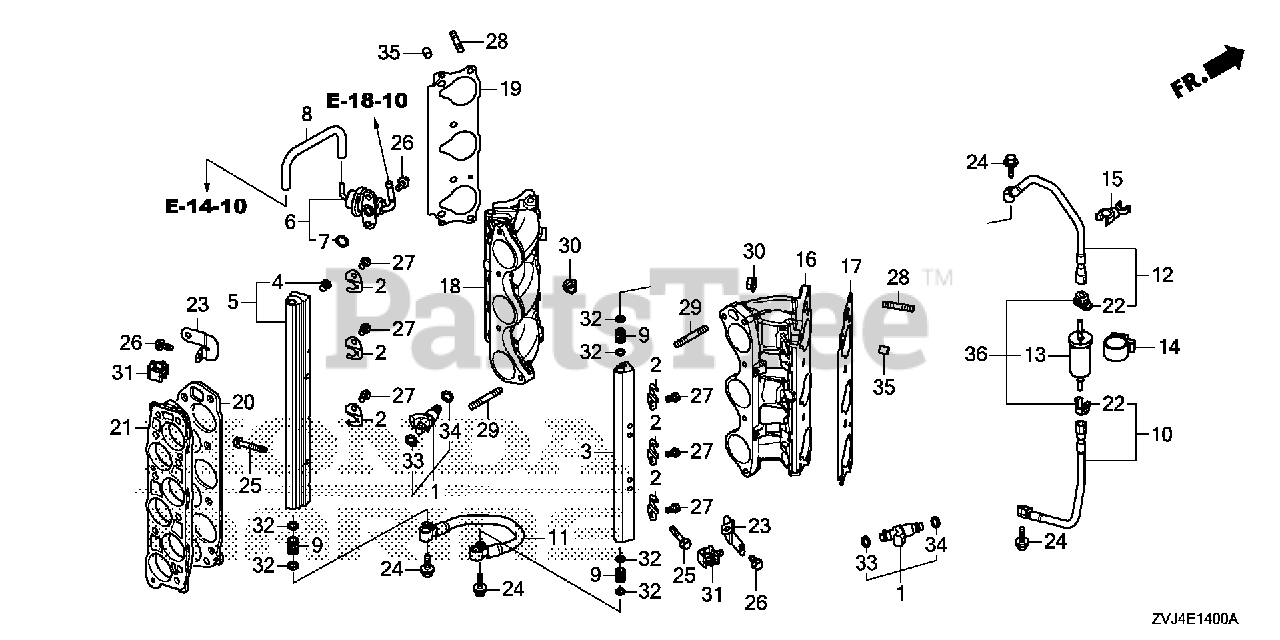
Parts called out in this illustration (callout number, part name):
1	INJECTOR ASSY., FUEL
2	CLIP, INJECTOR
3	PIPE, R. FUEL
4	MESH, FUEL FILTER
5	PIPE, L. FUEL
6	REGULATOR ASSY., PRESSURE
7	O-RING, PRESSURE REGULATOR
8	TUBE, PRESSURE REGULATOR CONTROL
9	JOINT, FUEL PIPE
10	HOSE, FUEL
11	HOSE, FUEL JOINT
12	HOSE B, FUEL
13	STRAINER, FUEL (HIGH)
14	SUSPENSION, STRAINER
15	CLAMP, HOSE
16	BASE, R. INJECTOR
17	GASKET, FR. INJECTOR BASE
18	BASE, L. INJECTOR
19	GASKET, RR. INJECTOR BASE
20	GASKET, IN. MANIFOLD
21	SPACER, IN. MANIFOLD
23	BRACKET, HARNESS CLIP A
24	BOLT, FLANGE (6X25)
25	BOLT, FLANGE (6X35)
26	BOLT, FLANGE (6X14)
27	BOLT, FLANGE (6X10)
28	BOLT, STUD (8X28)
29	BOLT, STUD (8X45)
30	NUT, FLANGE (8MM)
31	CLIP, WIRE HARNESS (10MM)
32	O-RING (7.8X1.9) (ARAI)
33	O-RING (7.47X3.6)
34	O-RING (7.45X3.61) (NOK)
35	PIN, DOWEL (10X12)
36	FILTER ASSY., FUEL (HIGH)
